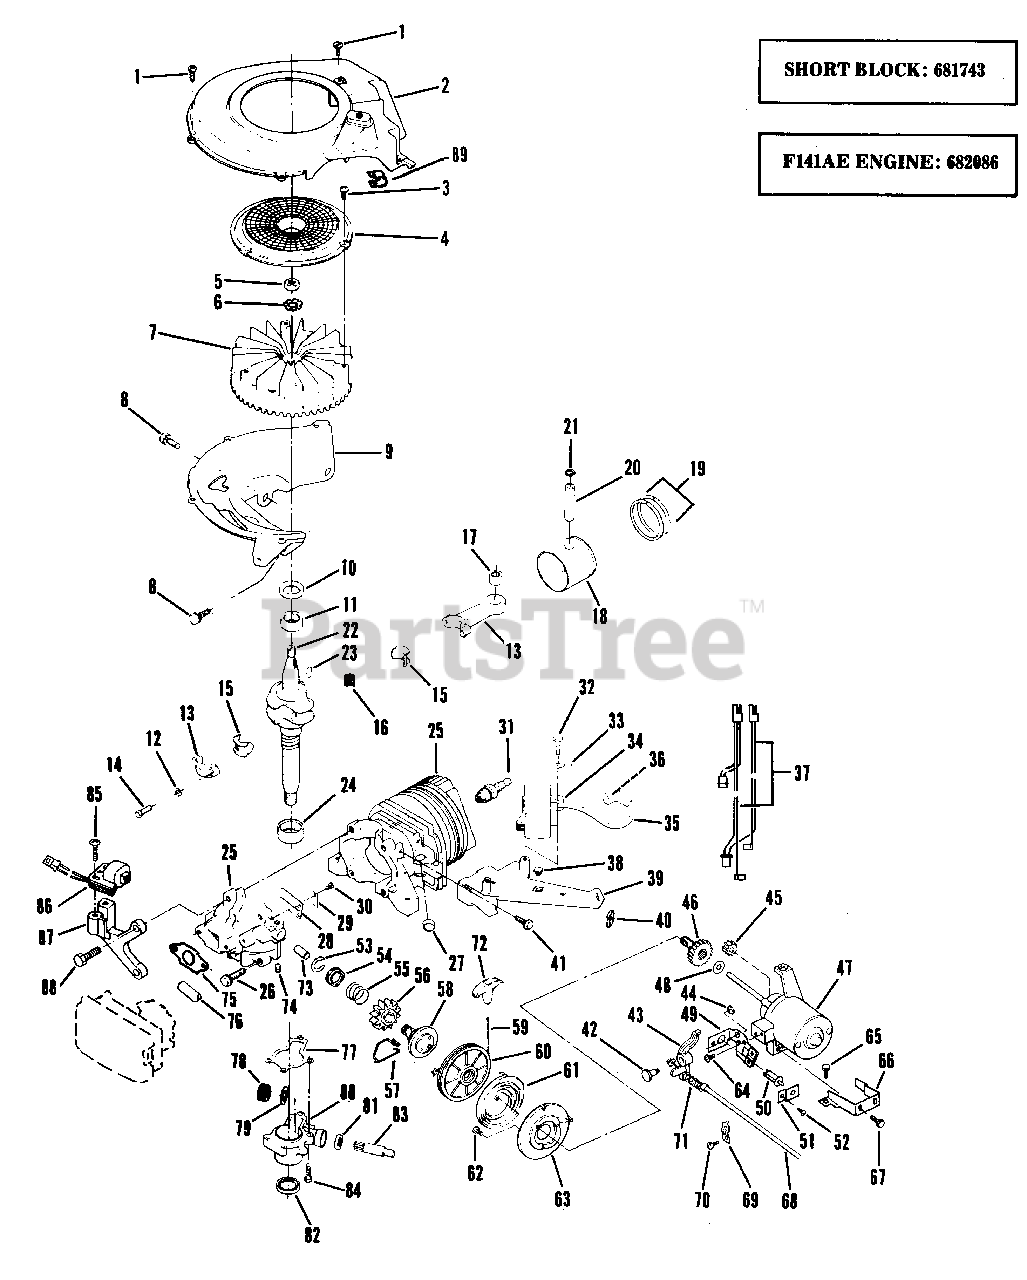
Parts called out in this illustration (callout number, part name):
1	Screw
2	Air Baffle & Eyelet Assembly
3	Screw-Flywheel Screen
4	Screen-Flywheel
5	Nut-Flywheel
6	Lockwasher
7	Flywheel Assembly
8	Screw
9	Base-Shroud
10	Oil Seal-Upper
11	Bearing-Upper
12	Lockplate
13	Connecting Rod Assembly
14	Screw
15	Liner-Split
16	Needle Bearing Set
17	Bearing Assembly
18	Piston & Ring Set
19	Ring Set
20	Wrist Pin
21	Retaining Ring
22	Crankshaft
23	Key-Flywheel
24	Bearing-Lower
25	Cylinder & Crankcase Cover Assembly
26	Screw-Cover to Crankcase
27	Plug
28	Reed
29	Plate-Reed Hold Down
30	Screw-Reed to Crankcase Cover
31	Spark Plug
32	Screw-C.D. Mounting
33	Terminal-Ignition
34	C.D. Ignition Module & Lead Assembly
35	High Tension Lead
36	Spring Terminal
37	Wire Harness & Terminal Assembly-Battery
38	Grommet-C.D. Bracket
39	Bracket-C.D.Mounting
40	Clip-"U"
41	Screw
42	Pin-Interlock
43	Lever-Interlock
44	Retaining Ring
45	Gear-Driven
46	Pinion-Motor Shaft
47	Motor & Gear Housing Assembly
48	Thrust Washer
49	Bracket
50	Switch Assembly
51	Plate-Switch Retaining
52	Screw
53	Ring-Retaining
54	Stopwasher
55	Spring-Pinion Return
56	Pinion
57	Spring-Drag
58	Clutch Assembly
59	Rope-Starter
60	Pulley & Clutch Assembly
61	Spring-Rewind
62	Screw-Cover to Housing
63	Gear Cover
64	Screw
65	Screw
66	Bracket-Starter Mounting
67	Screw-Bracket to Motor
68	Cable-Interlock
69	Clip
70	Screw-Clip-Cable
71	Spring
72	Handle-Starter-Manual
73	Sleeve-Starter Pin
74	Set Screw-Starter Assembly
75	Gasket-Carburetor to Crankcase Cover
76	Fuel Line
77	Gasket-Gear Box
78	Gear
79	Washer-Thrust
80	Gear Box Assembly
81	Seal
82	Oil Seal-Lower
83	Driveshaft
84	Screw-Gear Box
85	Screw-Alternator Mounting
86	Alternator Assembly
87	Bracket-Alternator
88	Screw-Alternator Bracket Mounting
89	Clamp-Wire Harness
